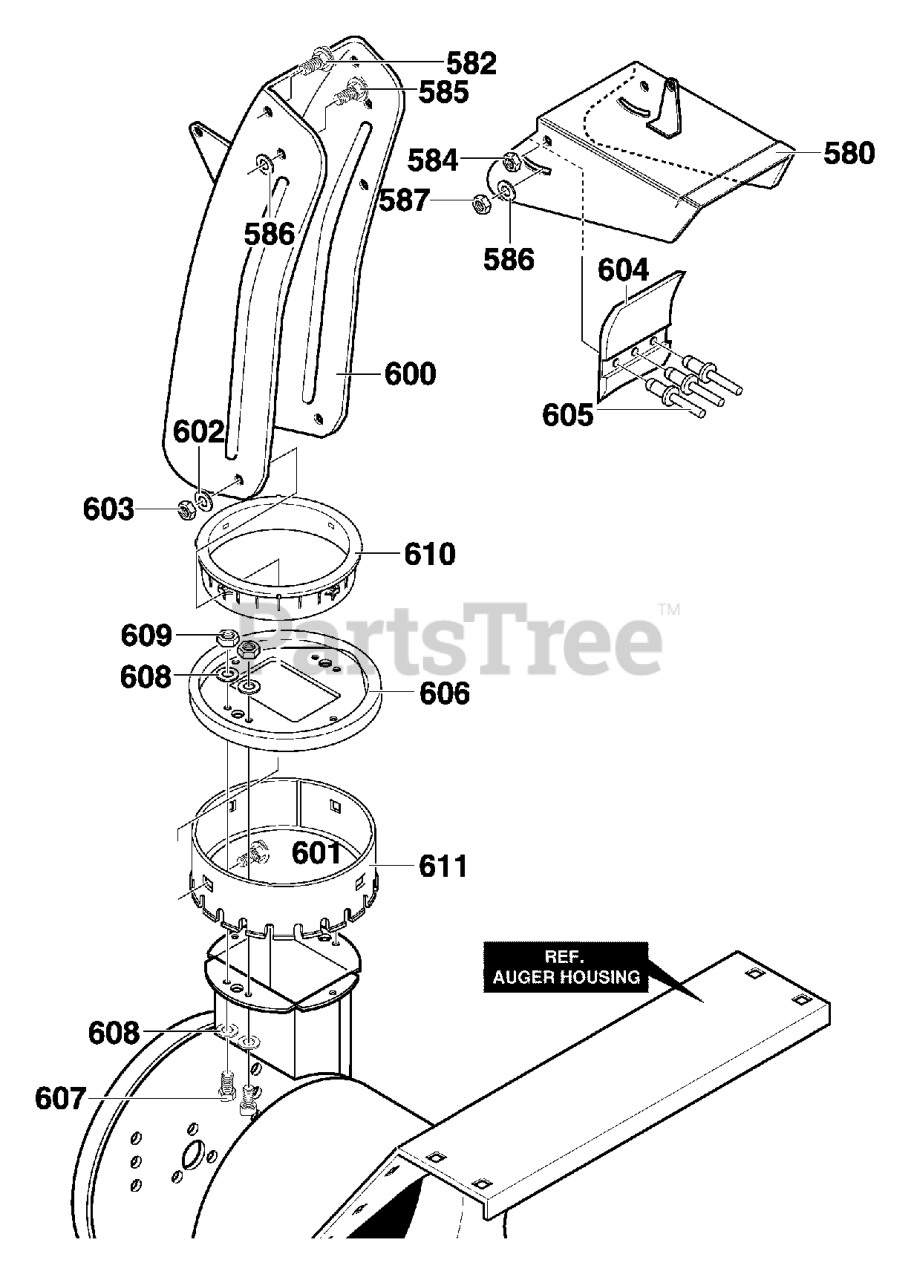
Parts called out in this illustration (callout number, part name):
580	ASSY., UPPER CHUTE
582	SCREW, 5/16-18 x 0.75
584	NUT, 5/16-18 HEX NYL
585	SCREW, 5/16-18 x 0.75
586	WASHER
587	NUT, 5/16-18 HEX NYL
600	LOWER CHUTE ASSEMBLY
601	BOLT, 5/16-18X1.00
602	FLATWASHER .349X.69X.066
603	NUT, 5/16-18
606	COLLAR, CHUTE
607	SCREW, 1/4-20X .75
608	FLATWASHER .281X .63X.065
609	NUT, 1/4-20 HEX NYLOCK
610	RETAINER, RING INNER
611	RETAINER, RING OUTER
